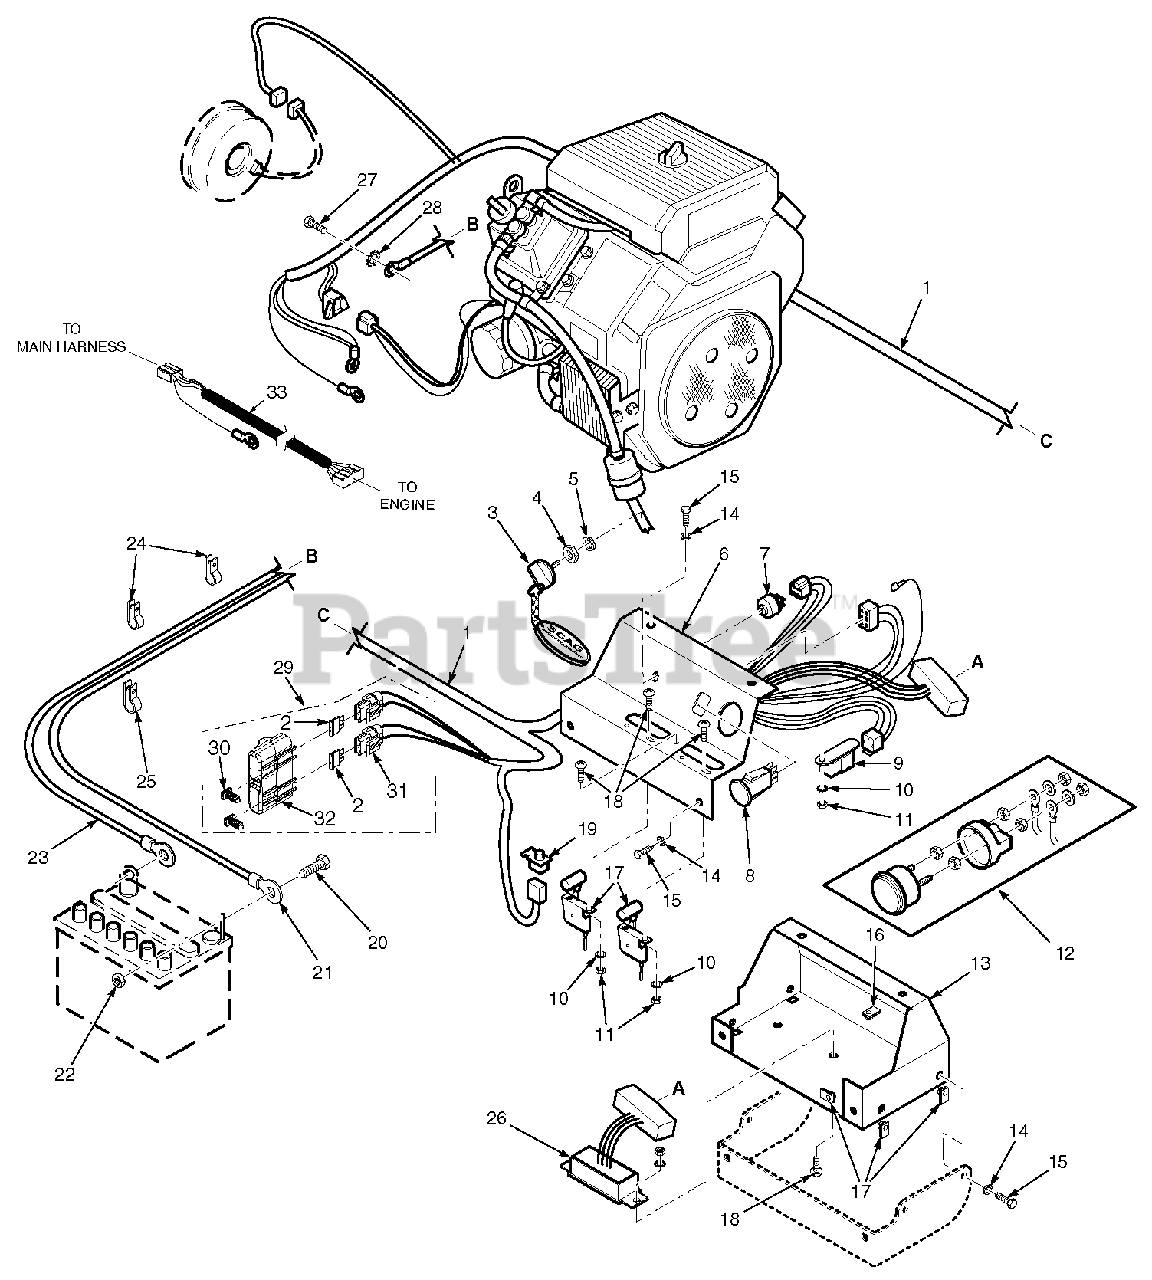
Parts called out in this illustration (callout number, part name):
1	Wire Harness, STT-BV/CH
2	Fuse, 20 AMP
3	Key, Ignition
3	Key Assembly w/Fob
4	Nut, Hex 5/8-32
5	Lockwasher, 5/8" Internal
6	Instrument Panel, Top w/Decals
7	Key Switch
8	Switch, PTO
9	Relay
10	Lockwasher, #10 External Tooth
11	Nut, Hex #10-32
12	Ammeter
13	Base, Instrument Panel
14	Lockwasher, 1/4"
15	Bolt, Hex Head 1/4-20 x 3/4"
16	U-Nut, 1/4-20
17	Throttle And Choke Controls (Kohler)
18	Screw, Phillips Washer Head #10-32 x 1/2"
19	Switch, Interlock-Seat
20	Bolt, Hex Head 1/4-20 x 1/2"
21	Cable, Battery - Red
22	Nut, Hex 1/4-20
23	Cable, Battery - Black
24	Clamp, Cable 1/2" ID.
25	Clamp, Cable 3/4" ID.
26	Electronic Module
27	Bolt, Hex Head M8-1.25 x 20mm
28	Lockwasher, 5/16" External Tooth
29	Double Fuse Assembly, Sealed
30	Clip, Wire
31	Fuse Holder
32	Cover, Sealed Double
33	Wire Harness Adapter, Kohler
